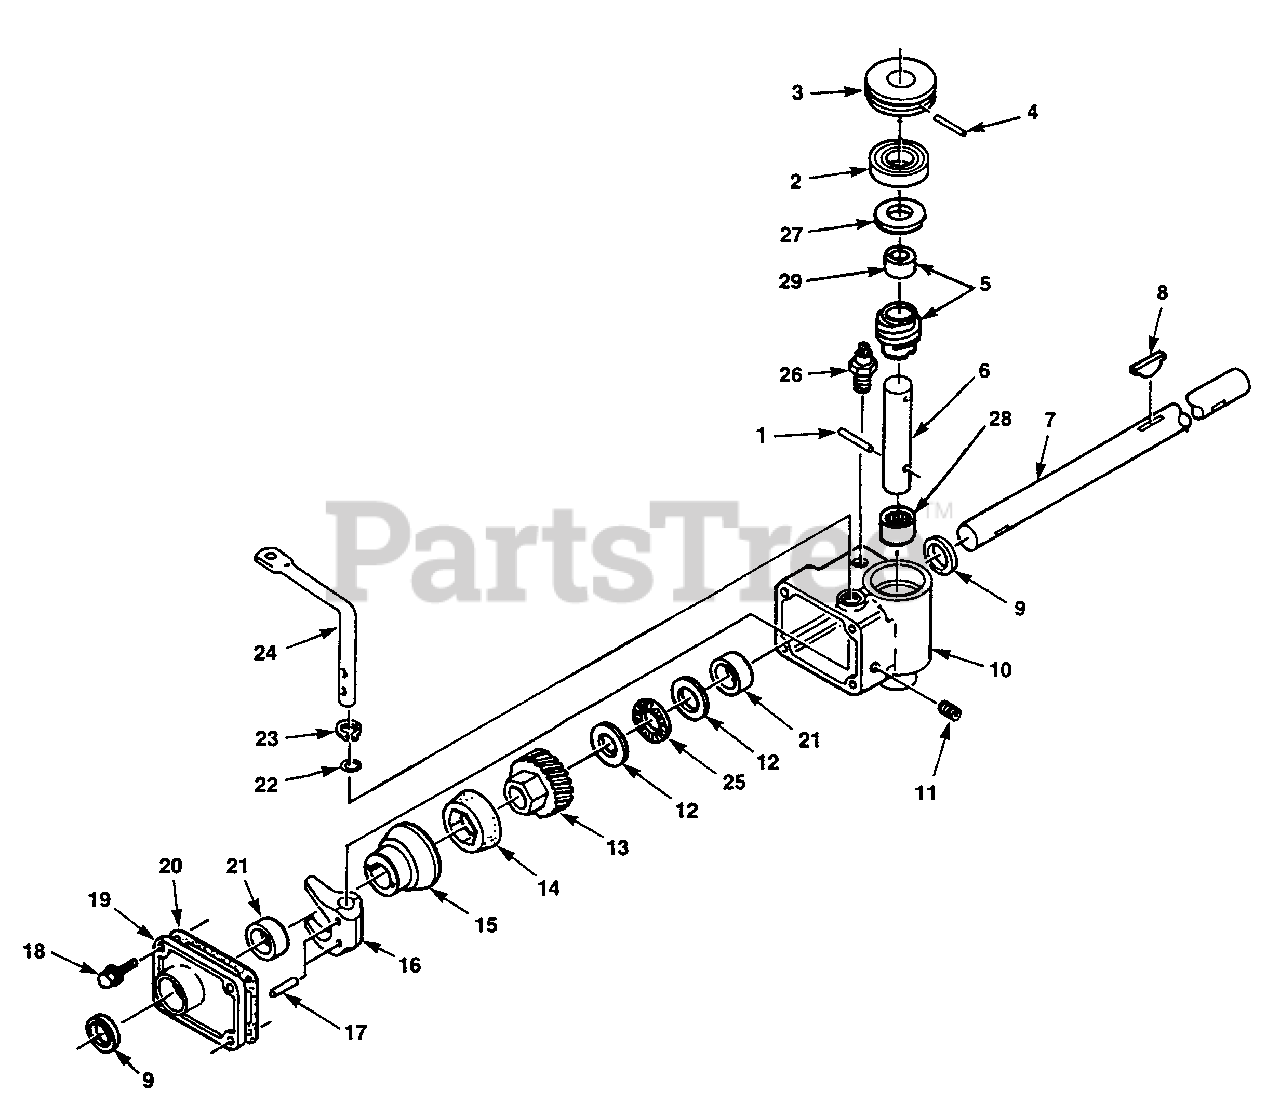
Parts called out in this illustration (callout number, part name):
1	PIN- Roll (3/16 x 7/8")
2	BEARING- Ball
3	PULLEY
4	PIN- Roll (3/32 x 1 1/4")
5	WORM & SPACER
6	SHAFT- Worm
7	SHAFT- Drive
8	KEY- (1/2 x 1/8")
10	GEAR REDUCER HOUSING ASSY.
11	PLUG- Pipe
12	RACE- Bearing thrust
13	GEAR- Helical
14	CONE- Friction
15	DRUM- Clutch
16	FORK- Shift
18	SCREW- (1/4-20 x 7/8")
19	COVER- Gearbox
20	GASKET- Gear box
21	BUSHING TBO
23	RING- Tru Arc
24	LEVER- Shift
25	BEARING- Thrust
26	VENT- Element filter
28	BEARING- Needle
29	SPACER- Worm gear
